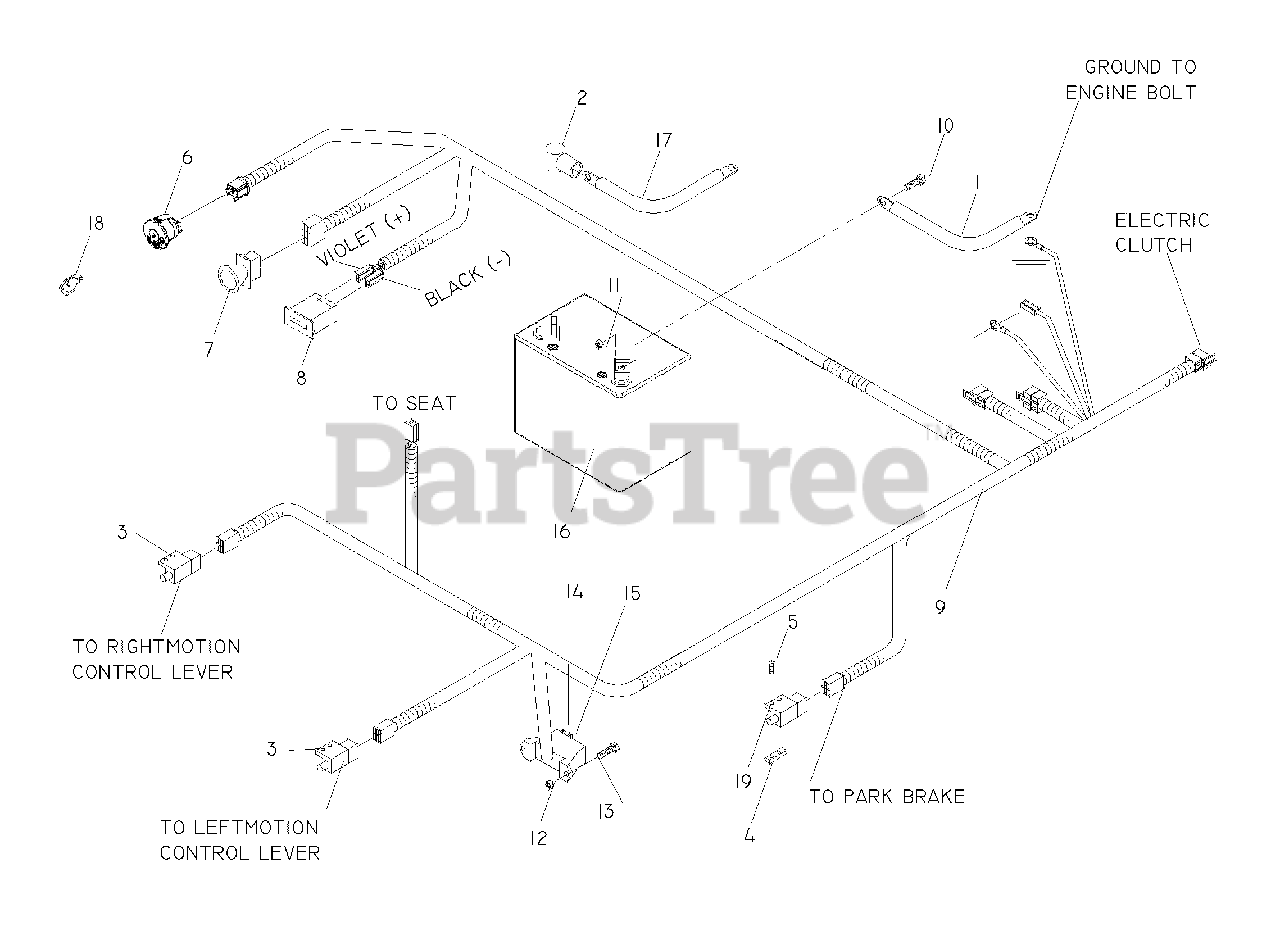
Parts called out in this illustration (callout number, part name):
1	CABLE-NEGATIVE
2	INSULATOR
3	SWITCH, INTERLOCK
4	TAPPED PLATE
5	SCREW #10-24 X 5/8
6	IGNITION SWITCH
7	SWITCH, BLADE
8	HOUR METER
9	HARNESS, KODIAK
10	HCS 5/16C X 3/4
11	NUT 5/16 NYLOC
12	NUT 10-24 NYLOC
13	SCREW, #1--24 X 1/2 SLOTTED
14	FUSE, 20 AMP 32 VOLT ATO
15	FUSE, 7.5 AMP 32 VOLT ATO
16	BATTERY, 12 V 330 AMP TBR
17	POSITIVE CABLE 25-1/2
18	KEY
19	SWITCH, INTERLOCK
